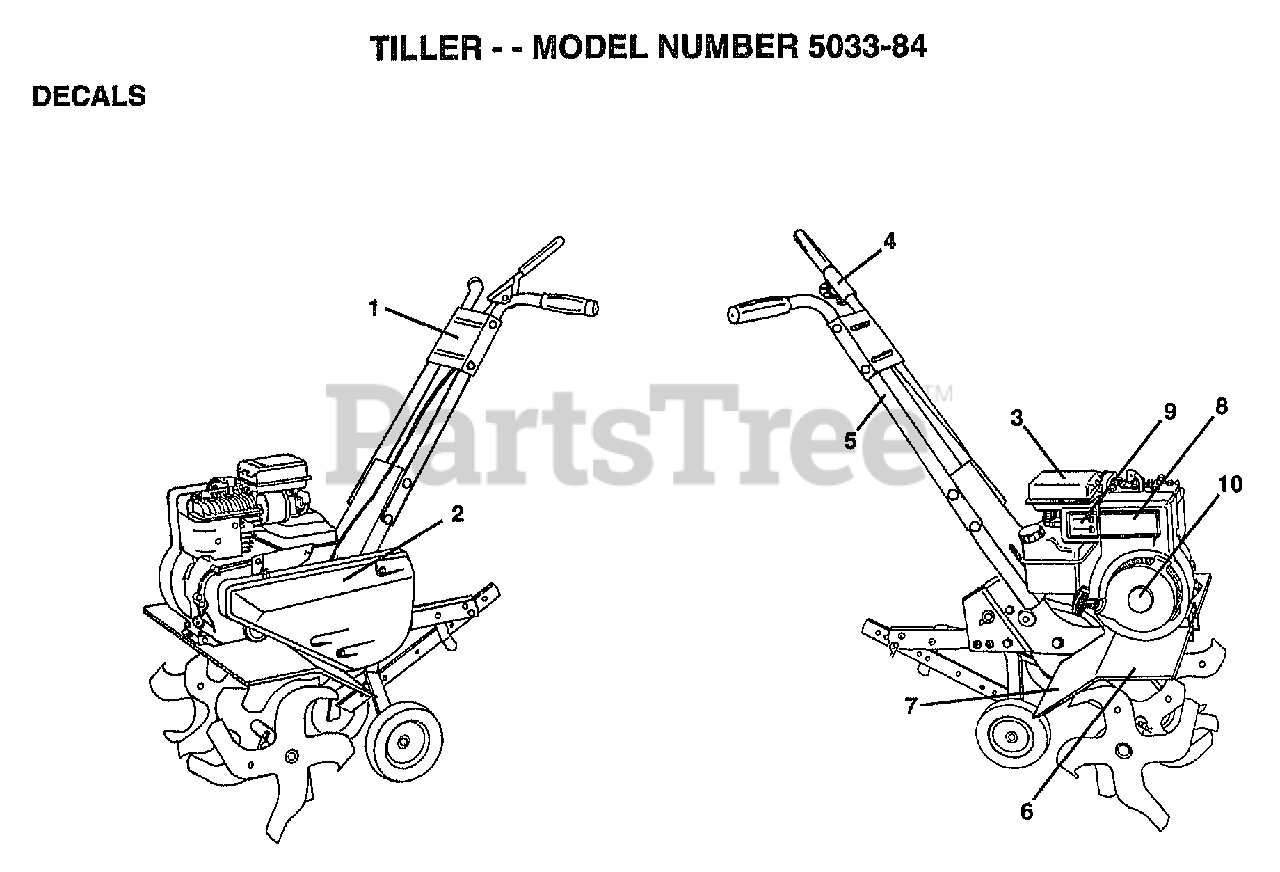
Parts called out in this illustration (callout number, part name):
1	DECAL.LOGO
4	DECAL TI
5	DECAL TI
6	DECAL.TINE.SHIELD
7	DECAL TI
8	DECAL-BRIGGS AND STRATTON
9	DECAL-SPEED CONTROL
10	DECAL-3.5 HP
